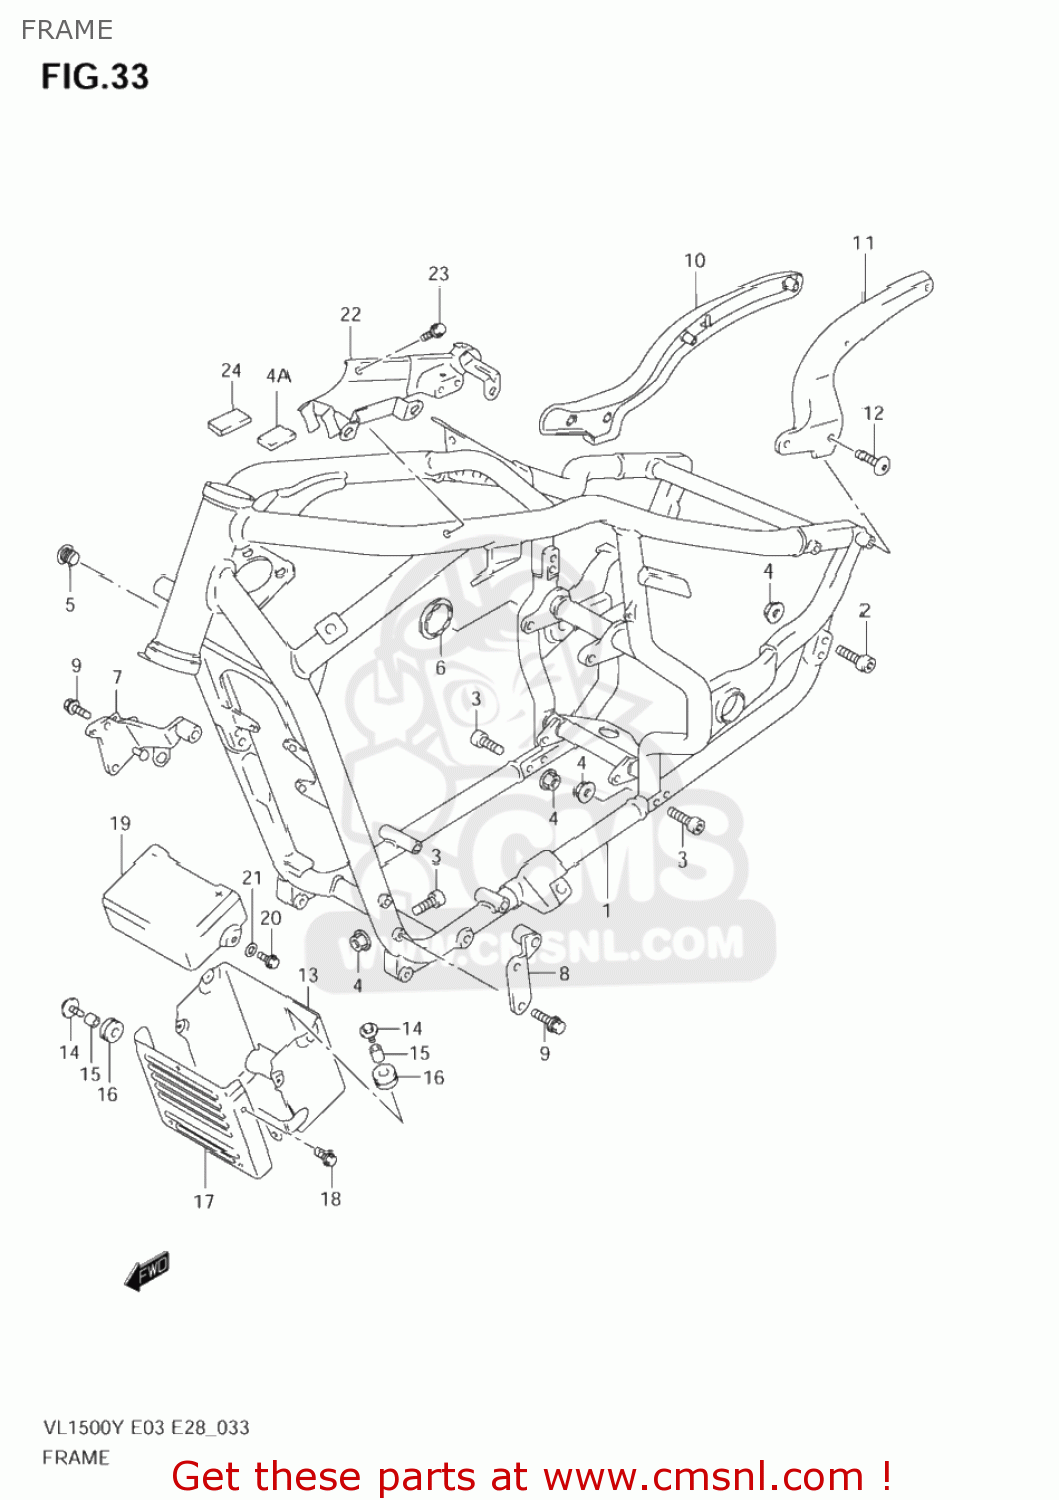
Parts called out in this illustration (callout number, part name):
1	FRAME(BLACK)
2	BOLT
3	BOLT
4	NUT
4A	CUSHION,CHAIN CASE
5	CAP,FRAME U-LOCK HOLE
6	CAP,FRAME PIVOT,R
7	PLATE,ENGINE MOUNT NO.1,R
8	PLATE,ENGINE MOUNTING NO.1,LEFT
9	BOLT
10	GRIP,FRAME HANDLE,R
11	GRIP,FRAME HANDLE,L
12	BOLT,HANDLE GRIP
13	HOLDER,BATTERY
14	BOLT(6X16)
15	SPACER(6.5X9X8)
16	CUSHION
17	HOLDER,BATTERY FR
18	SCREW
19	COVER,BATTERY,UPPER
20	BOLT
21	WASHER
22	PLATE COMP,ELECTRIC PARTS
23	BOLT
24	CUSHION
